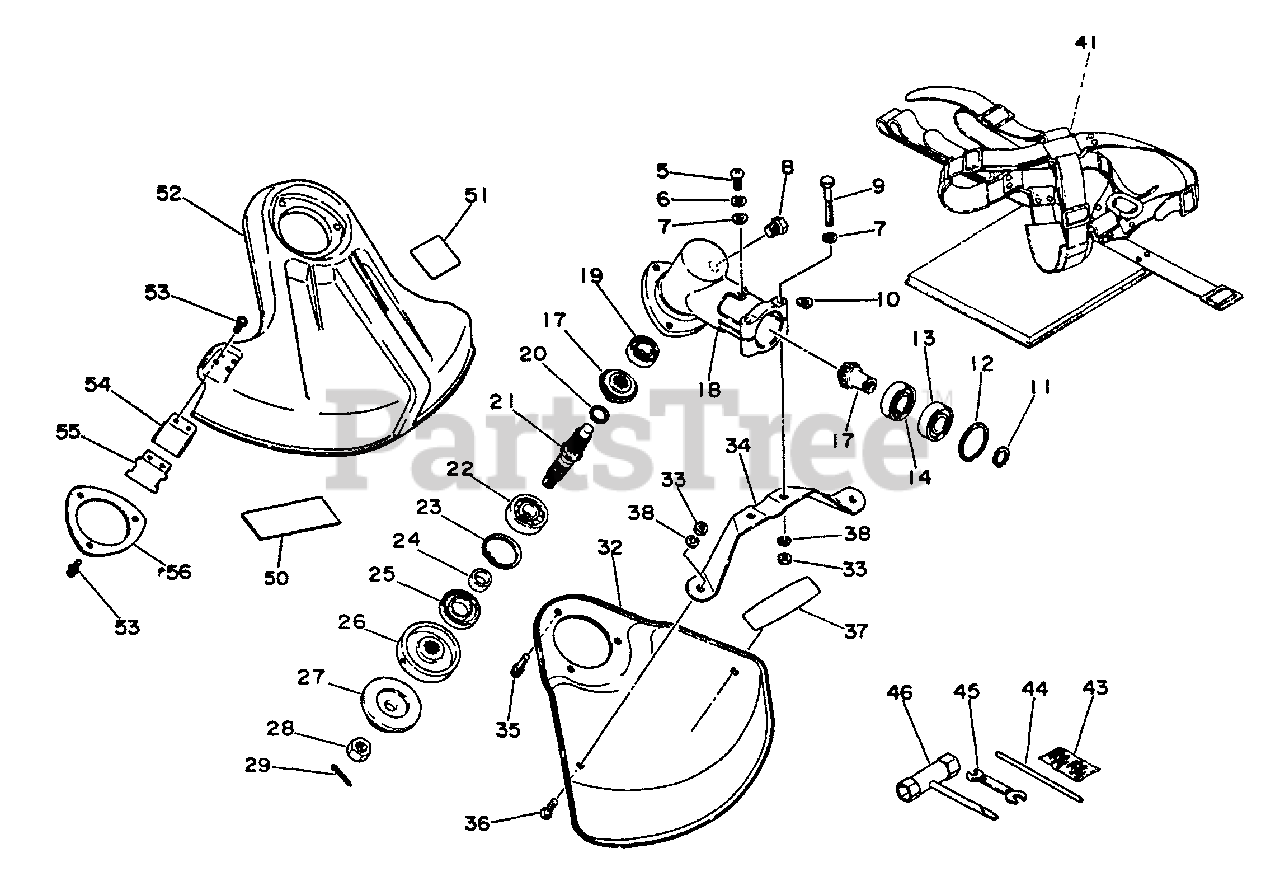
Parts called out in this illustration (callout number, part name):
5	SCREW - 5X10
6	GEAR CASE ASSY
7	WASHER - 5
8	BOLT - 8X8
9	BOLT - 5X40
11	RING, RETAINING - 12
12	RING, RETAINING - 28
13	BEARING, BALL - 6001
14	BEARING, BALL - 6001
17	GEAR SET - BEVEL
18	CASE, GEAR
19	BEARING, BALL - 6000
20	RING, RETAINING - 12
21	GEAR - SHAFT
22	BEARING, BALL - 6201
23	RING, RETAINING - 32
25	SEAL, OIL
26	ADAPTOR, BLADE - UPPER
27	ADAPTOR, BLADE - LOWER
28	NUT - 10 -- LEFT HAND
29	PIN, SPLIT - 2X22
32	SHIELD
34	BRACKET, SHIELD
35	SCREW - 5X10
36	SCREW - 5X8
37	LABEL - ECHO
38	LOCKWASHER - 5
41	SHOULDER STRAP ASSY
43	PIN, SPLIT - 2X22
44	LOCKING TOOL
45	SPANNER - 8X10mm
46	T-WRENCH
50	LABEL - ECHO
51	LABEL - CAUTION
52	SHIELD, DEBRIS - PLASTIC
53	KNIFE, TRIMMER LINE
54	GUARD
55	SCREW - 5X16
56	PLATE, SHIELD
